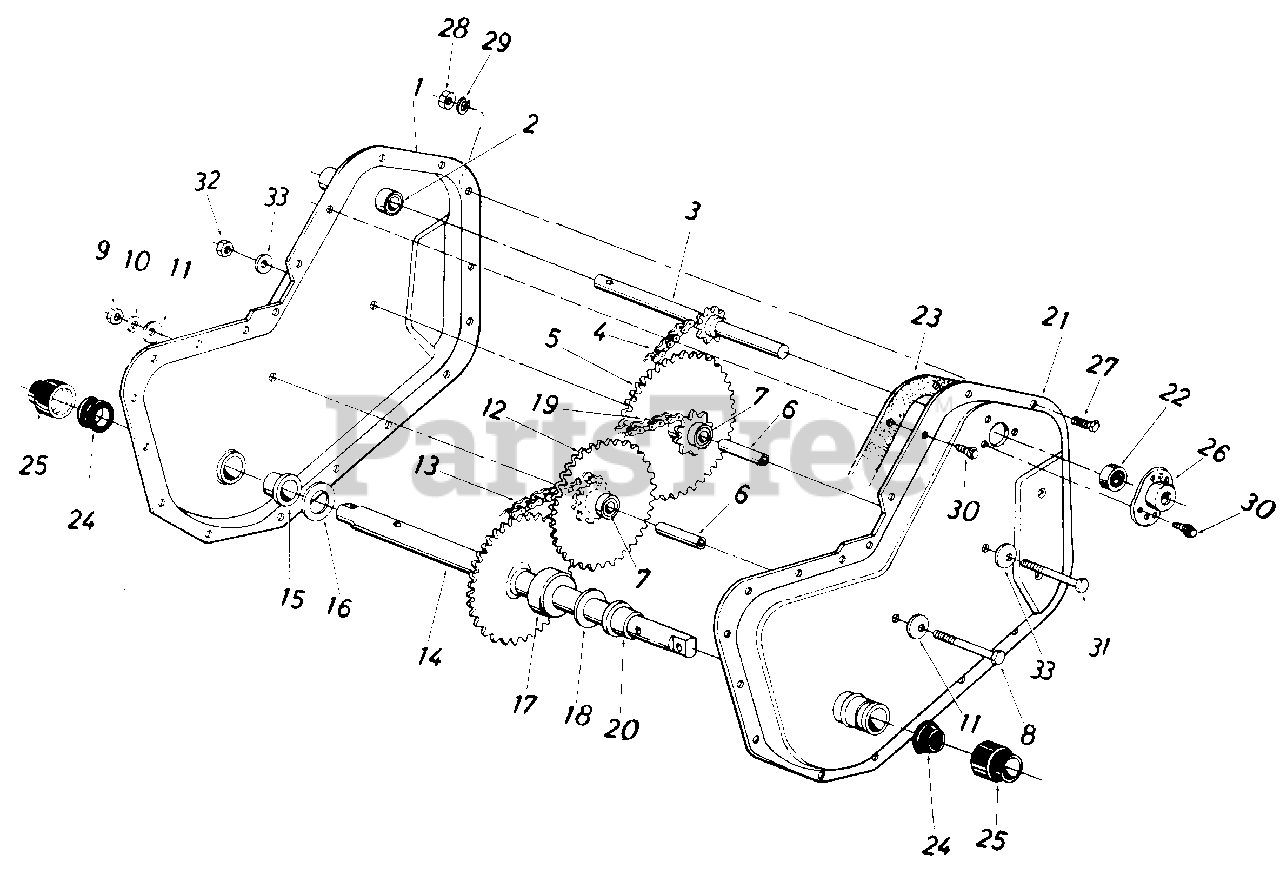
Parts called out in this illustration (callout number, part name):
1	Chain Case Half Ass'y. R.H.
2	Bearing 5/8" I.D. x .813" O.D. x 1.31" Lg.
3	Input Shaft Ass'y.
4	Chain #35 3/8" Pitch x 44 Links
5	Sprocket and Hub Ass'y.
6	Bearing Inner Axle
7	Sleeve Brg. 5/8" I.D. x 3/4" O.D. x 1.50
8	Hex Bolt 3/8-24 x 2.50" Lg.*
9	Hex Ins. L-Nut 3/8-24 Thd.
10	L-Wash. 3/8" I.D.*
11	Bell-Wash. .41" I.D. x 1.13" O.D. x .03
12	Sprocket & Hub Ass'y. 9T-22T
13	#420 Chain 1/2 Pitch x 28 Links Endless
14	Wheel Shaft Ass'y.
15	Flange Bearing
16	Fl-Wash. .88" I.D. x 1.5" O.D. x.03
17	Spacer 7/8" I.D. x 1 3/4" O.D. x.68" Lg.
18	Fl-Wash. .88" I.D. x 1.50" O.D. x .03
19	#420 Chain 1/2 " Pitch x 30 Links Endless
20	Flange Bearing
23	Gasket
25	Dust Cup
26	Bearing Housing
27	Hex Bolt 1/4-28 x 5/8" Lg.
28	Hex Nut 1/4-28 Thd.
29	L-Wash. 1/4" I.D.*
30	Hex Wash. S-Tap Scr. 1/4-20 x.50" Lg.
31	Hex Bolt 5/16-18 x 2.5" Lg.
32	Hex Cent. L-Nut 5/16-18 Thd.
33	Fl.-Wash. 5/16" I.D.
